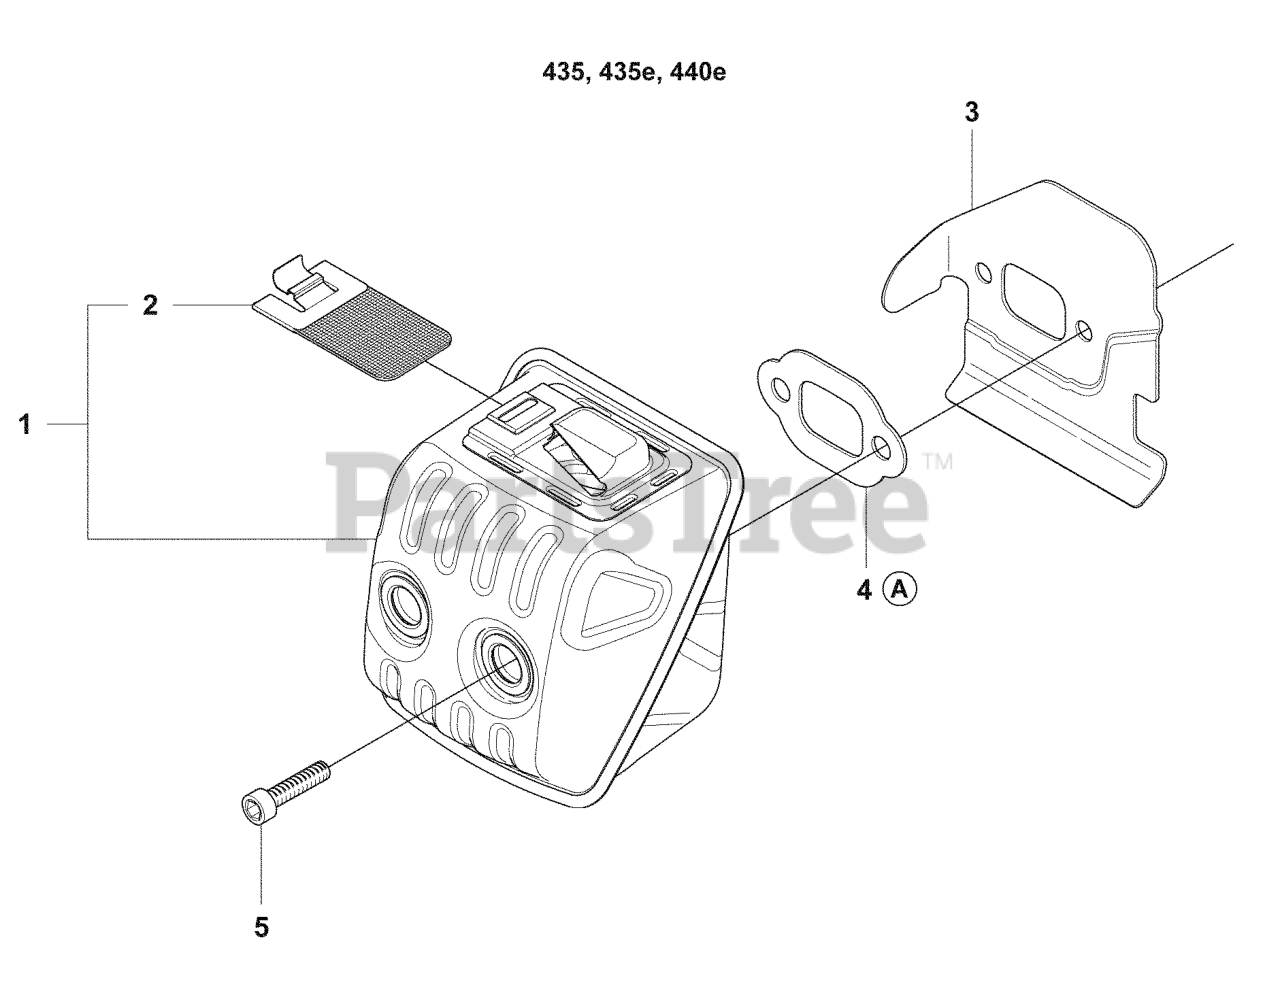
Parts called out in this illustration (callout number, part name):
1	%MUFFLER ASSY
2	SPARK ARRESTER
3	HEAT DEFLECTOR
4	RP GASKET
5	SCREW MC6S 6X16
